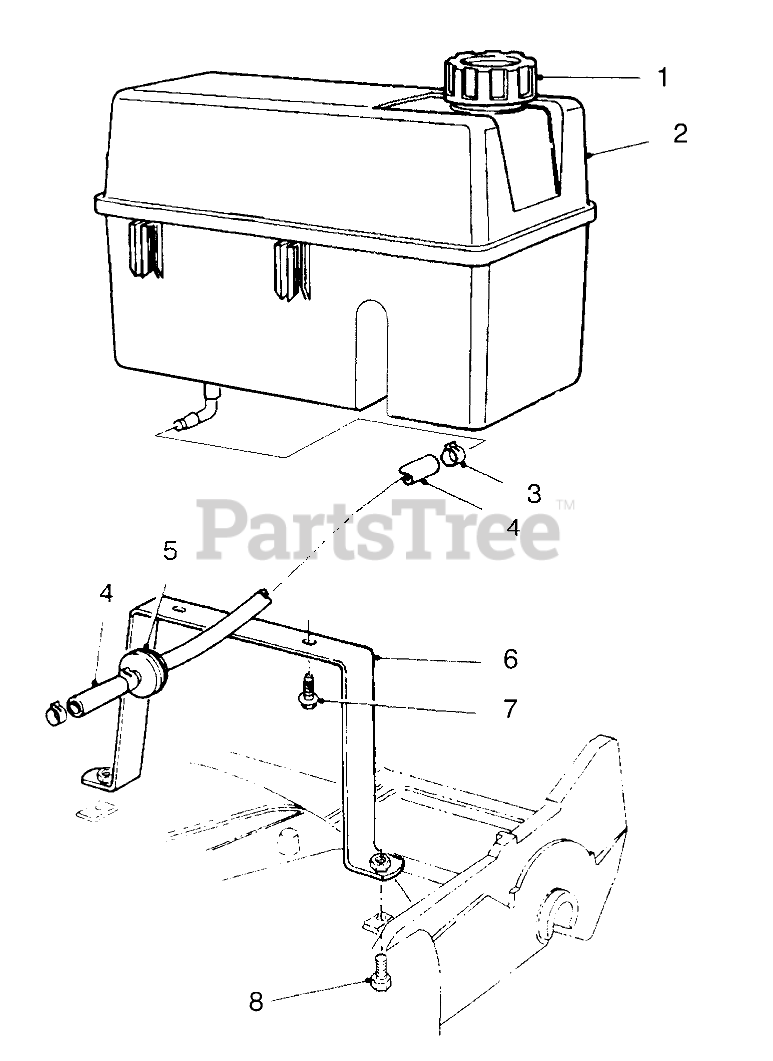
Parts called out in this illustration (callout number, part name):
1	GAS CAP ASM
2	TANK - FUEL
3	CLAMP-FUEL LINE
4	HOSE-FUEL
5	FILTER-FUEL
6	Wa-Base
7	SCREW-HWH
8	SCREW-HH
